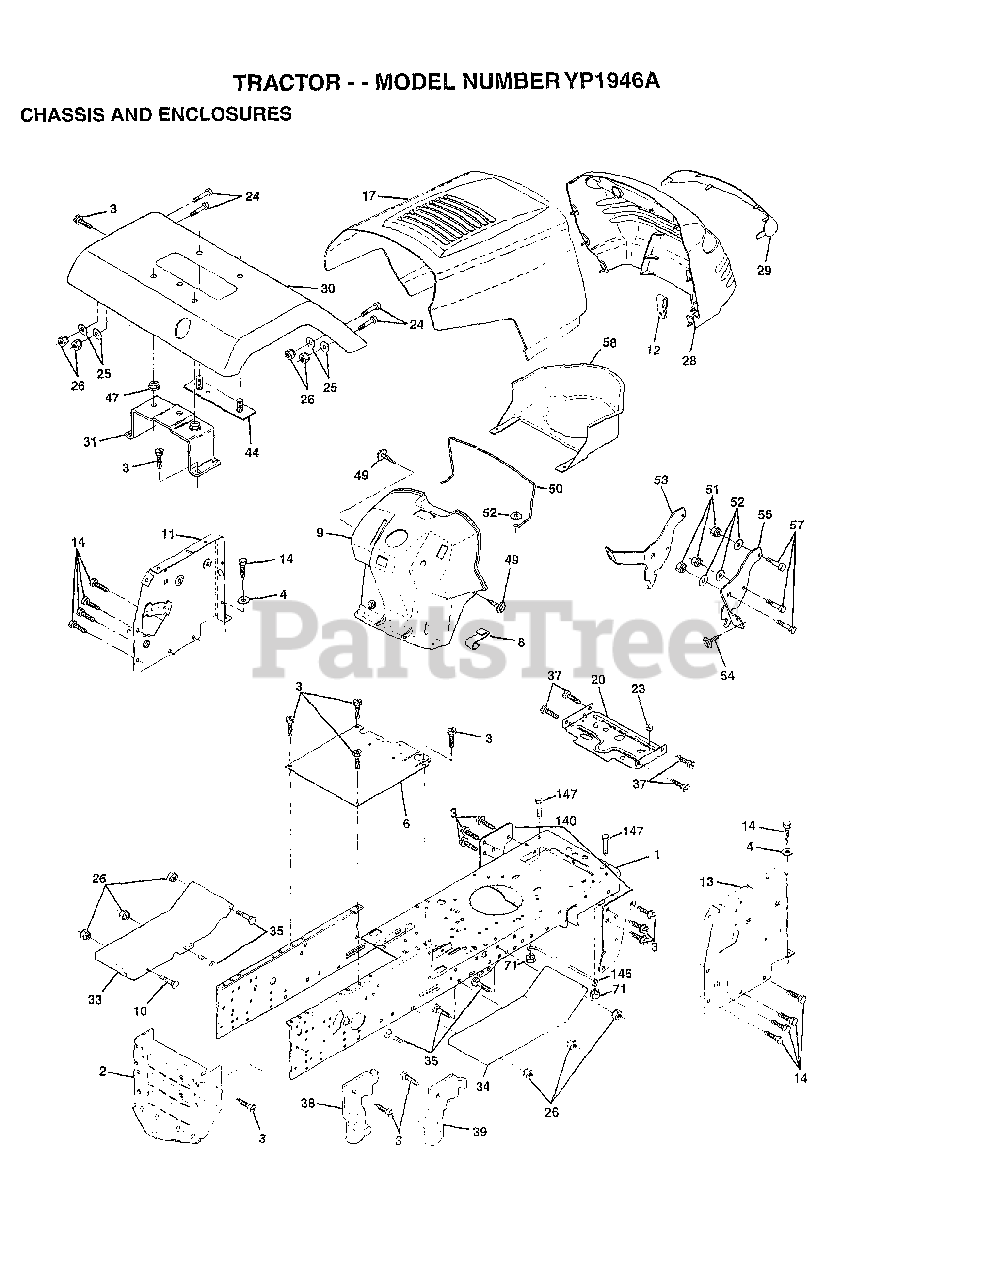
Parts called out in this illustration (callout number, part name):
1	CHASSIS ASM
3	SCREW
4	WASHER
6	SADDLE
8	"CLIP,INSULATOR"
9	DASH.PRVT.LBL.
11	PANEL DASH ASM
12	CLIP.TINNERMAN
13	"PANEL DASH,RH"
14	SCREW LT
20	"PLATE-MTG,BATT/FU"
24	BOLT
25	WASHER
26	NUT
28	GRILL
29	LENS.EURO.W/DECAL
30	"FENDER WS,FTK"
31	BRKT.ASM.FENDER
33	FOOTREST PNT LH
34	FOOTREST.RH.LT/GT
35	BOLT
37	SCREW LT
38	BRACKET ASM LH
39	BRACKET ASM RH
44	STRAP ASM FENDER
47	NUT-PUSH YT
49	SCREW HEX CRT
50	"ROD SUPPORT,DASH"
51	NUT
52	WASHER
53	BRACKET.GRILLE.LH
55	BRACKET.GRILLE.RH
58	CAP ASM FUEL
140	BRKT SUSPENSION
145	"ROD POVOT,CHASSIS"
